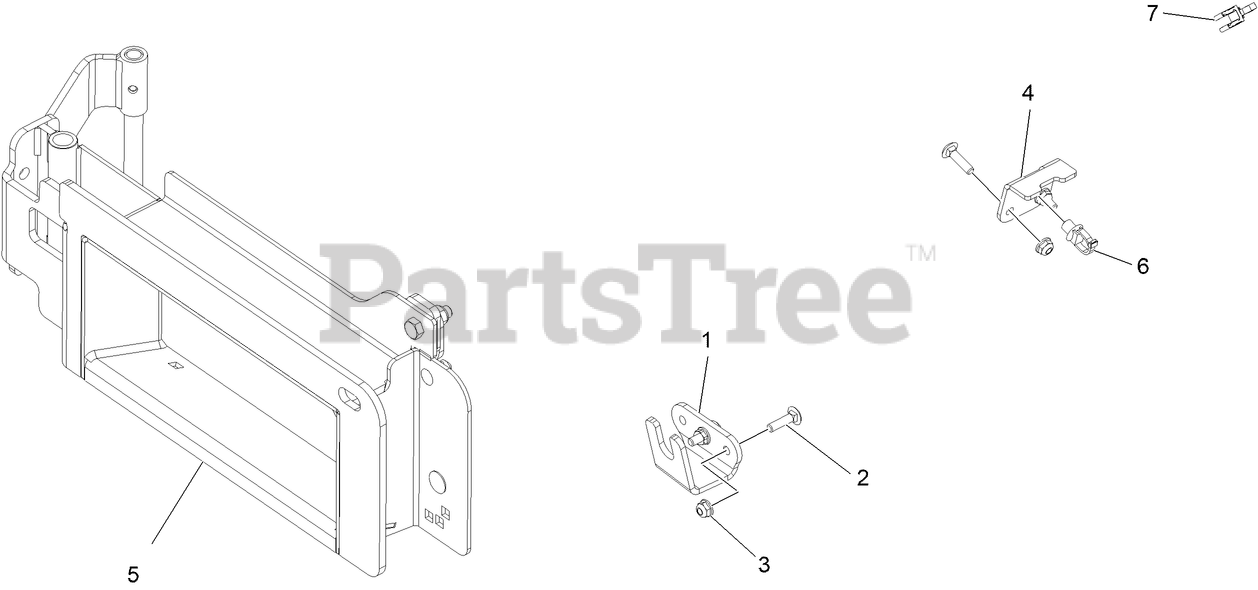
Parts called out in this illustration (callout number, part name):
1	BRKT-OCD CABLE
2	SCREW-CARR
4	BRKT-CABLE
5	KIT-ADAPTOR, ACCY. (SERIES 3)
6	CLIP-TIE
7	Clip-Edge
